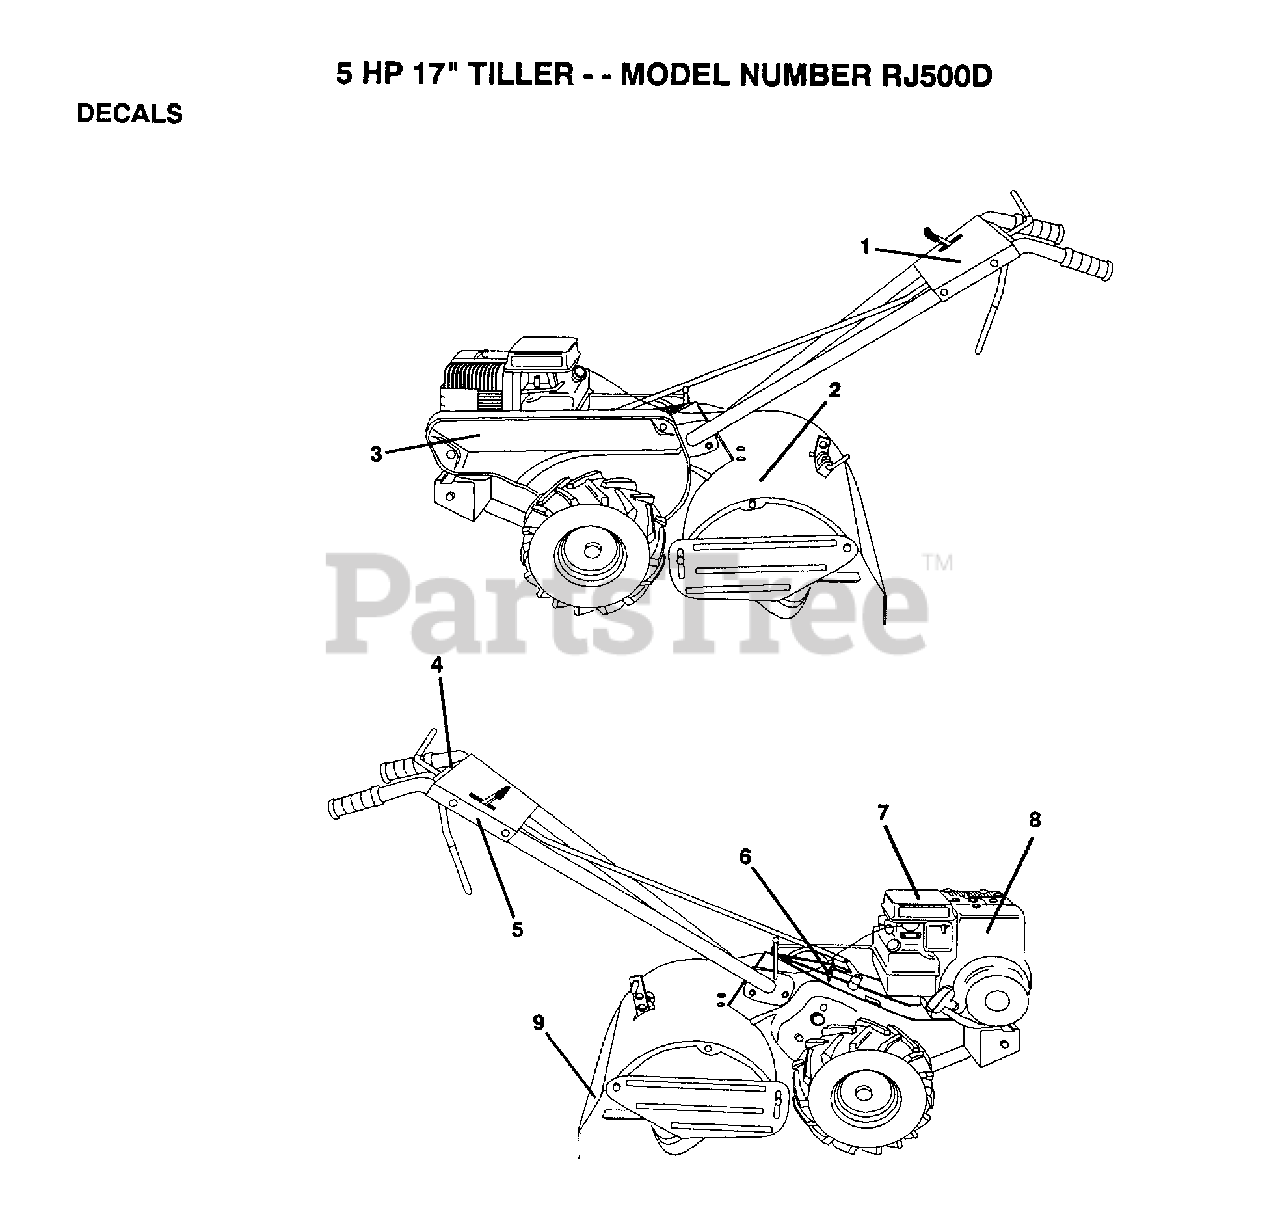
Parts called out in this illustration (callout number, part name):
3	DECAL, LOGO
5	DECAL TI
7	DECAL TI
